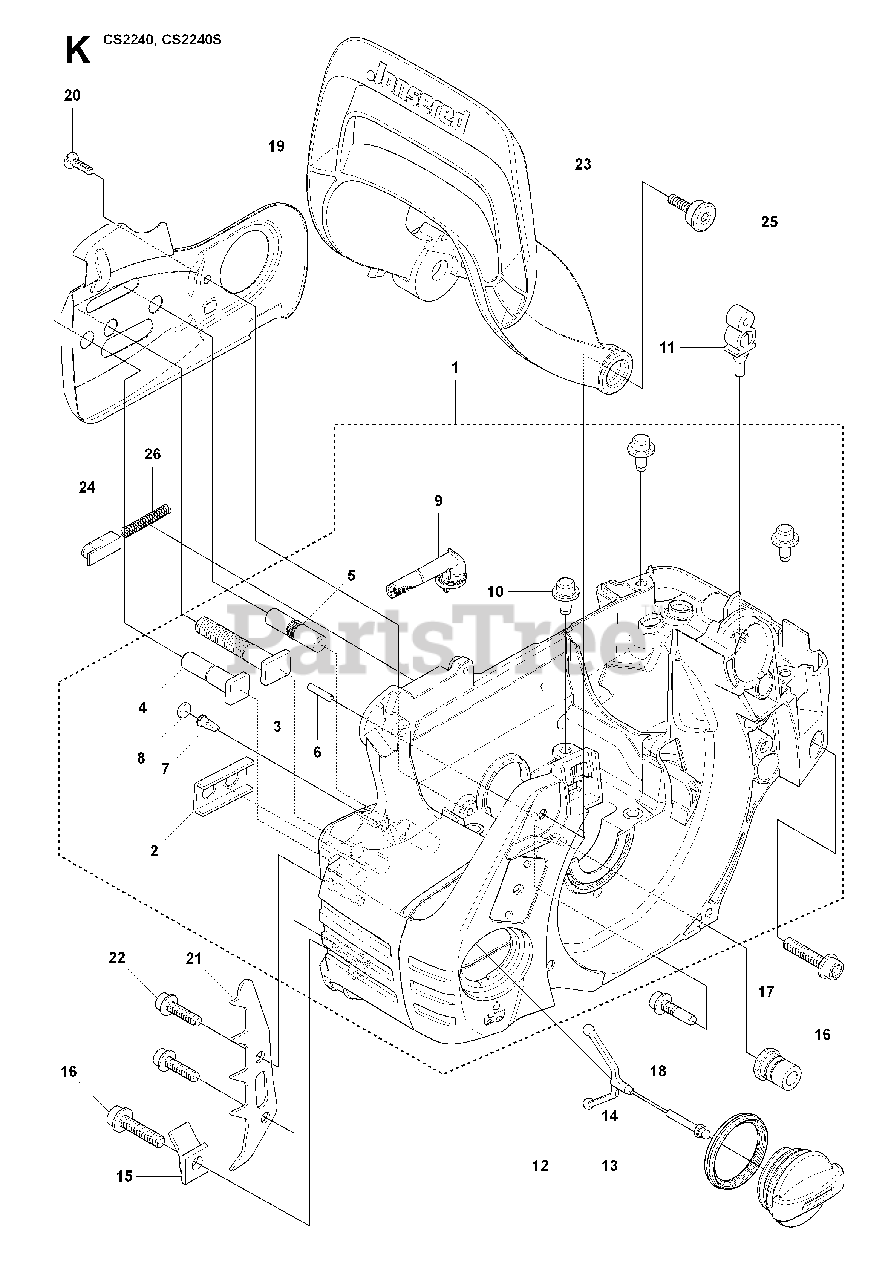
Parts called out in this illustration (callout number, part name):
1	CRANKCASE ASSY
2	STIFFENING PLATE
4	BAR BOLT (X2)
7	VALVE-CHECK (DUCKBILL)
8	PLUG
9	OIL SCREEN
10	GUIDE PEN
12	TANK CAP ASSY
13	SEALING
15	CHAIN CATCHER
16	SCREW IHSCFT
17	LATERAL SUPPORT
18	SCREW IHSCFT
19	CHAIN GUIDE PLATE
21	SPIKE INNER
25	SCREW
26	LOCK SPRING
